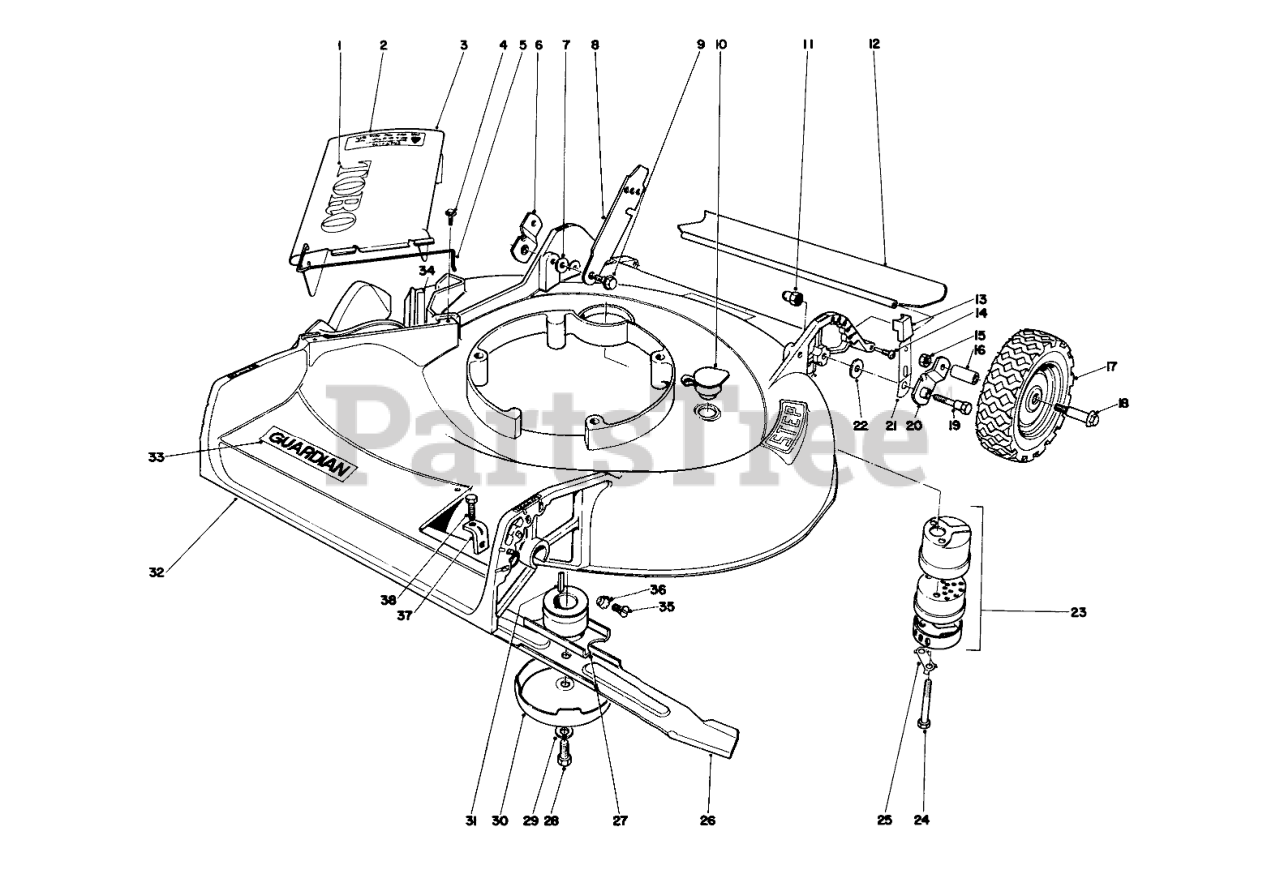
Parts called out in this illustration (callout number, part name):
1	TORO LOGO DECAL
2	Caution Decal
3	Deflector Cover (Incl. Ref. #1, 2 & 5)
4	SCREW
5	SPRING HINGE
6	Pivot Arm
7	SPACER
8	Latch
9	SCREW-SHOULDER
10	WASHOUT PLUG
11	HANDLE PIVOT NUT
12	REAR SAFETY SHIELD 21
13	Knob
14	SAFTEY SHIELD SCREW
15	Nut
16	Bushing
17	Wheel Assembly (Incl. Ref. #16)
19	5/16-18 PIVOT SCREW
20	Pivot Arm
21	SPRING ARM ASM
22	WASHER-PIVOT
23	Muffler Assembly (Incl. Ref. #24-25)
24	SCREW-HH
25	CLIP - LOCKING
26	Blade
27	Blade Retainer
28	SPECIAL SCREW
29	WASHER-LOCK
30	AntiScalp Cup
31	KEY-SQUARE
32	Housing
33	Decal
34	Decal
35	5/16-18X5/8 FLT HD MS
36	Lockwasher
37	ADJ BRACKET
38	SCREW-HH
